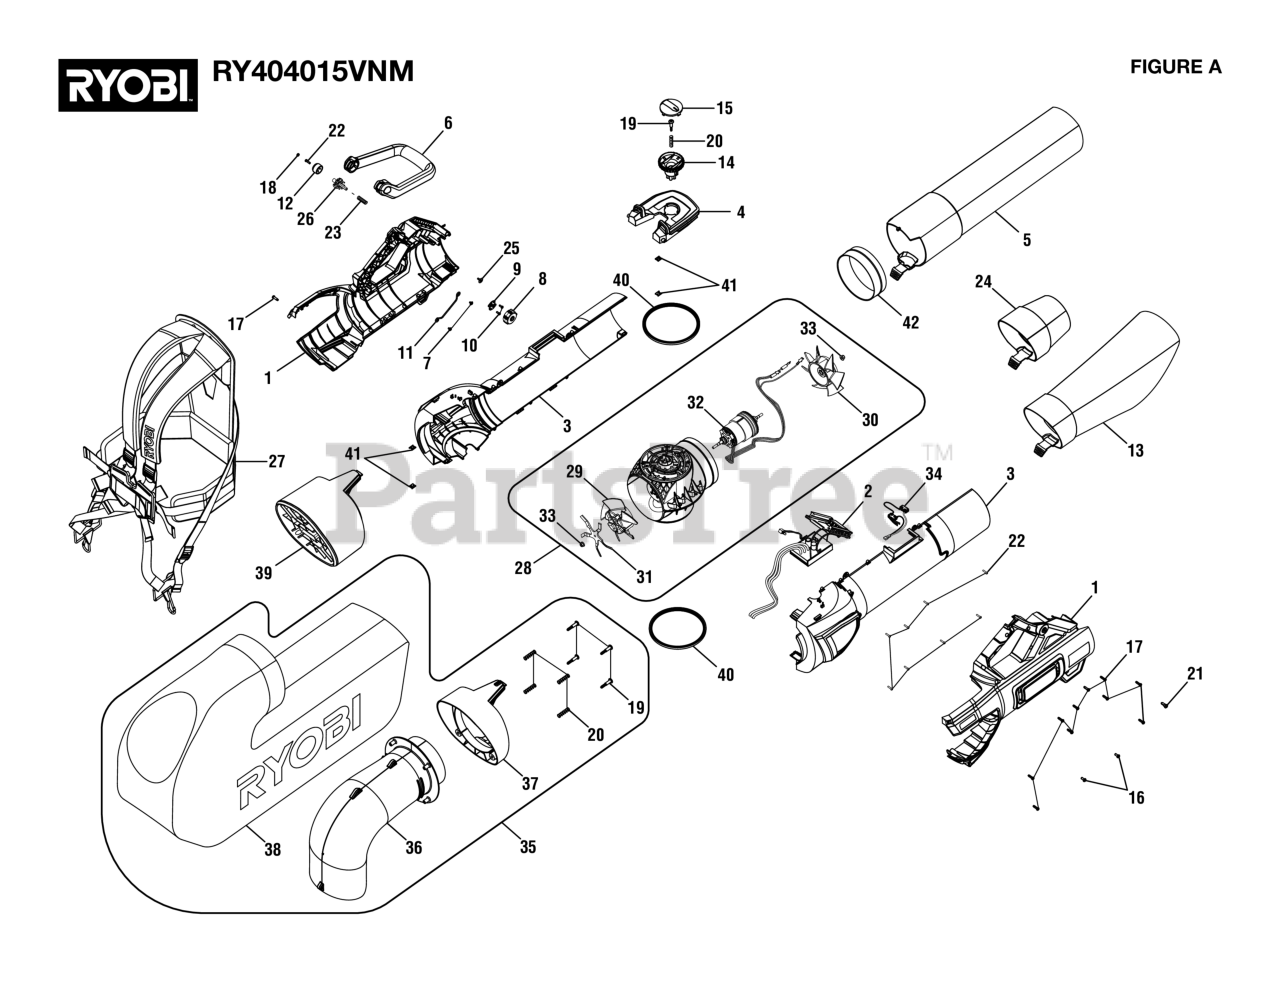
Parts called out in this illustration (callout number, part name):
1	Handle Housing Assembly (Inc. Labels)
2	Motor Contoller & Battery Foot Assembly
3	Ball Cover Assembly
4	Strap Housing Assembly (Inc. Labels)
5	Tube Assembly
6	Support Handle
7	Screw (M3 x 5 mm)
8	Speed Dial
9	Switch Plate
10	Screw (M3 x 8 mm, Torx T10)
11	Grounding Strap
12	Hinge Knob
13	Vacuum Nozzle
14	Rotating Knob
15	Rotating Knob Cap
16	Screw (M4 x 9 mm)
17	Screw (M4 x 14 mm, T15 Torx Pan Hd.))
18	Tamper Indicator Plug
19	Screw (M5 x 27 mm)
20	Spring,Handle Cover, Dia. 7, SWC
21	Screw (M5 x 15 mm, T25 Torx Hd.)
22	Screw (M3 x 12 mm)
23	Compression Spring
24	Blower Nozzle
25	ST SCREW,STEEL CH M3.0X1.058 PWH PHILIP
26	Hinge Knob Cap
27	Shoulder Harness
28	Ball Assembly
29	Fan (Stage 1)
30	Fan (Stage 2)
31	Mulching Blade
33	Flange Lock Nut (M5 x 0.8 in.)
34	Safety Switch And Wires Assembly
35	Vac Attachment Assembly
36	Leaf Exit Tube
37	Vacuum Bag Holder
39	Blower Attachment Assembly
41	Housing Connection Clip
